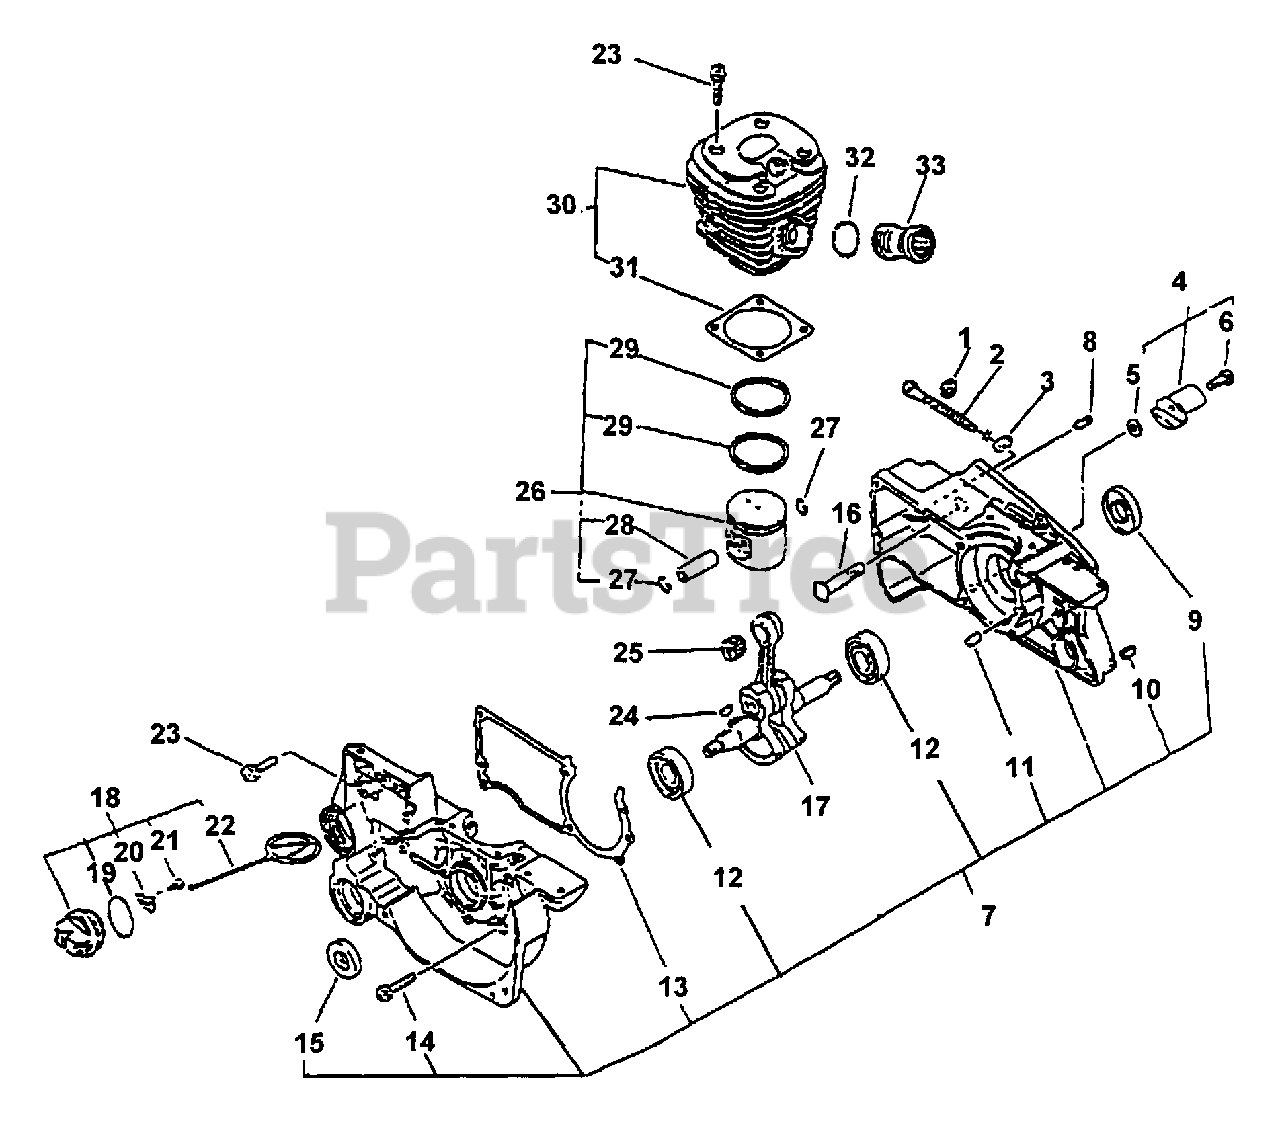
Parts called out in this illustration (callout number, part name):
2	SCREW, CHAIN TENSION
3	TENSIONER, CHAIN
4	CHAIN CATCHER KIT
5	WASHER, FLAT 5.5×10×0.8
6	SCREW 5×18
7	CRANKCASE KIT
8	VENT ASSY
9	SEAL, OIL
10	PIN, SPRING 5×10
11	PIN, LOCATING 5×10
12	BEARING, BALL 6202
13	GASKET, CRANKCASE
14	BOLT 5×30
15	SEAL, OIL
16	STUD, GUIDE BAR 8
17	CRANKSHAFT
18	CAP ASSY, OIL
20	RETAINER, CONNECTOR
21	SCREW, TAPPING 3×8
22	CONNECTOR, CAP L= 60 MM
23	BOLT 5×20
24	KEY, WOODRUFF
25	BEARING, NEEDLE
26	PISTON KIT
27	RING, SNAP 8
28	PIN, PISTON
29	RING, PISTON
30	CYLINDER KIT
31	GASKET, CYLINDER
32	BAND
33	ADAPTOR, INTAKE
